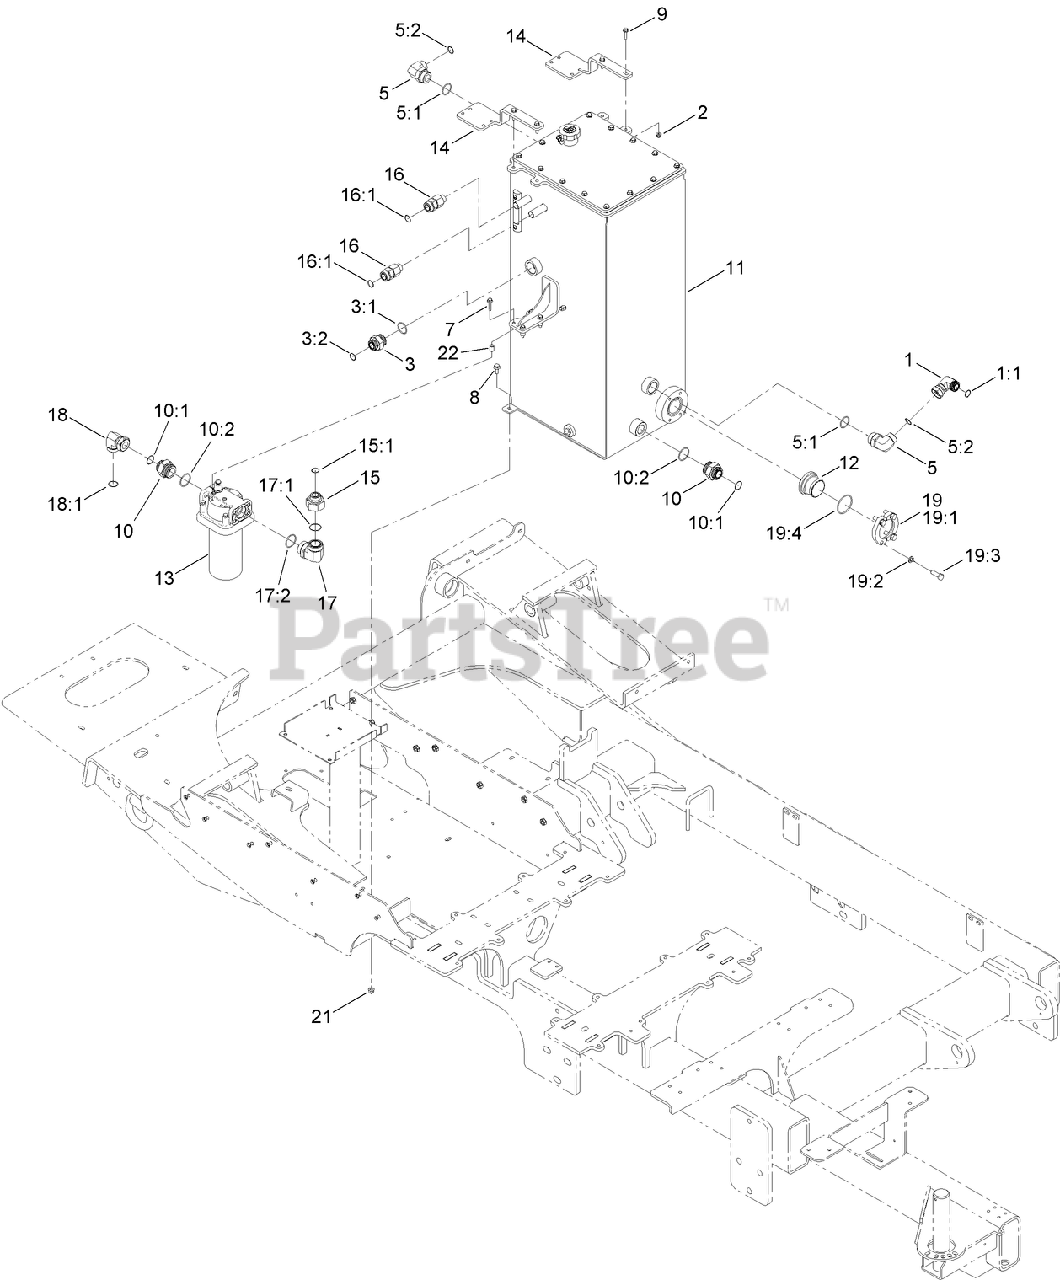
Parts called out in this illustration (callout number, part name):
1	FITTING-SWIVEL, 90 DEG
1:1	O-RING
2	NUT-LOCK, HHF
3	FITTING-STR
3:1	O-RING
3:2	O-RING
5	FITTING-ELBOW 90
5:1	O-RING
5:2	O-RING
7	SCREW-HHF, LOCKING
8	SCREW-HHF
9	SCREW-HHF
10	FITTING-STR
10:1	O-RING
10:2	O-RING
11	HYD TANK ASM
12	INSERT
13	FILTER-HYD, RETURN
14	MOUNT-PLATE
15	FITTING-REDUCER
15:1	O-RING
16	FITTING-STRAIGHT
16:1	O-RING
17	FITTING-ELBOW 90
17:1	O RING
17:2	O-RING
18	FITTING-ELBOW, 90
18:1	O-RING
19	SPLIT FLANGE KIT
19:1	Flange
19:2	WASHER-LOCK
19:3	SCREW-HH
19:4	O-RING
21	NUT-LOCK, NI
22	SPACER-WHEEL
